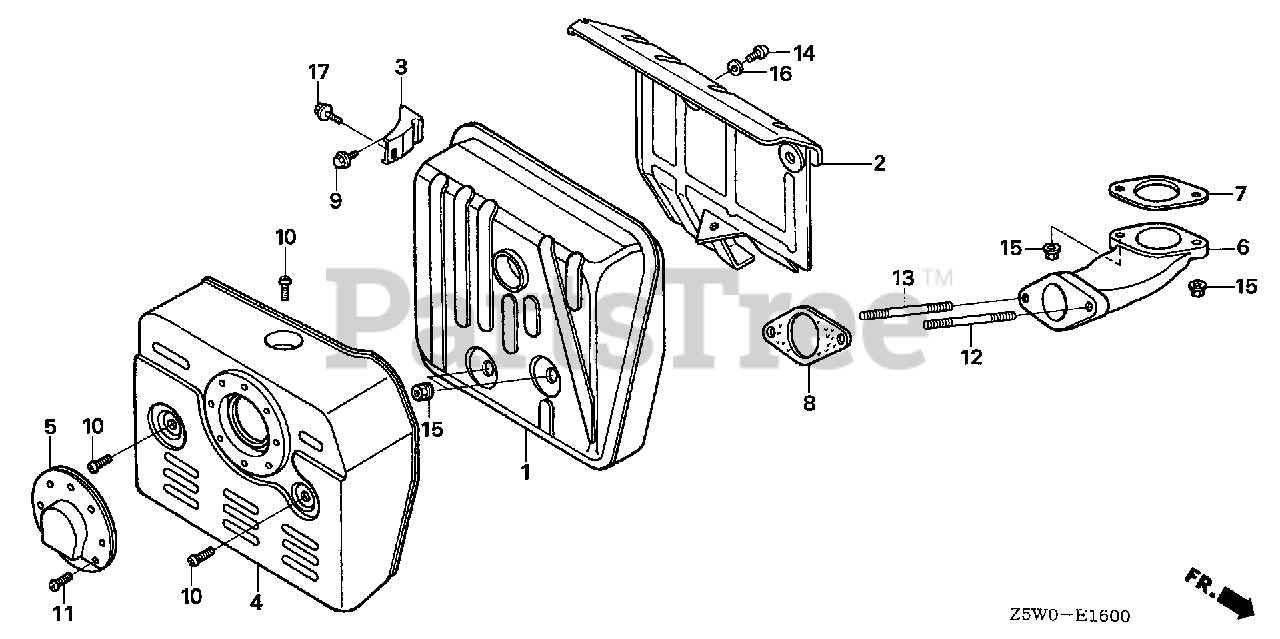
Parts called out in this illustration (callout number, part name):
1	MUFFLER
2	SEPARATOR, MUFFLER
3	STAY, MUFFLER
4	PROTECTOR, MUFFLER
5	CAP, MUFFLER
7	GASKET, EX. PIPE
8	GASKET, EX. PIPE
9	BOLT, FLANGE (8X16)
10	SCREW, TAPPING (5X8)
11	SCREW, TAPPING (4X6)
12	BOLT, STUD (8X60)
13	BOLT, STUD (8X70)
14	SCREW, PAN (6X6)
15	NUT, FLANGE (8MM)
16	WASHER, PLAIN (6MM)
17	BOLT, FLANGE (8X14)
